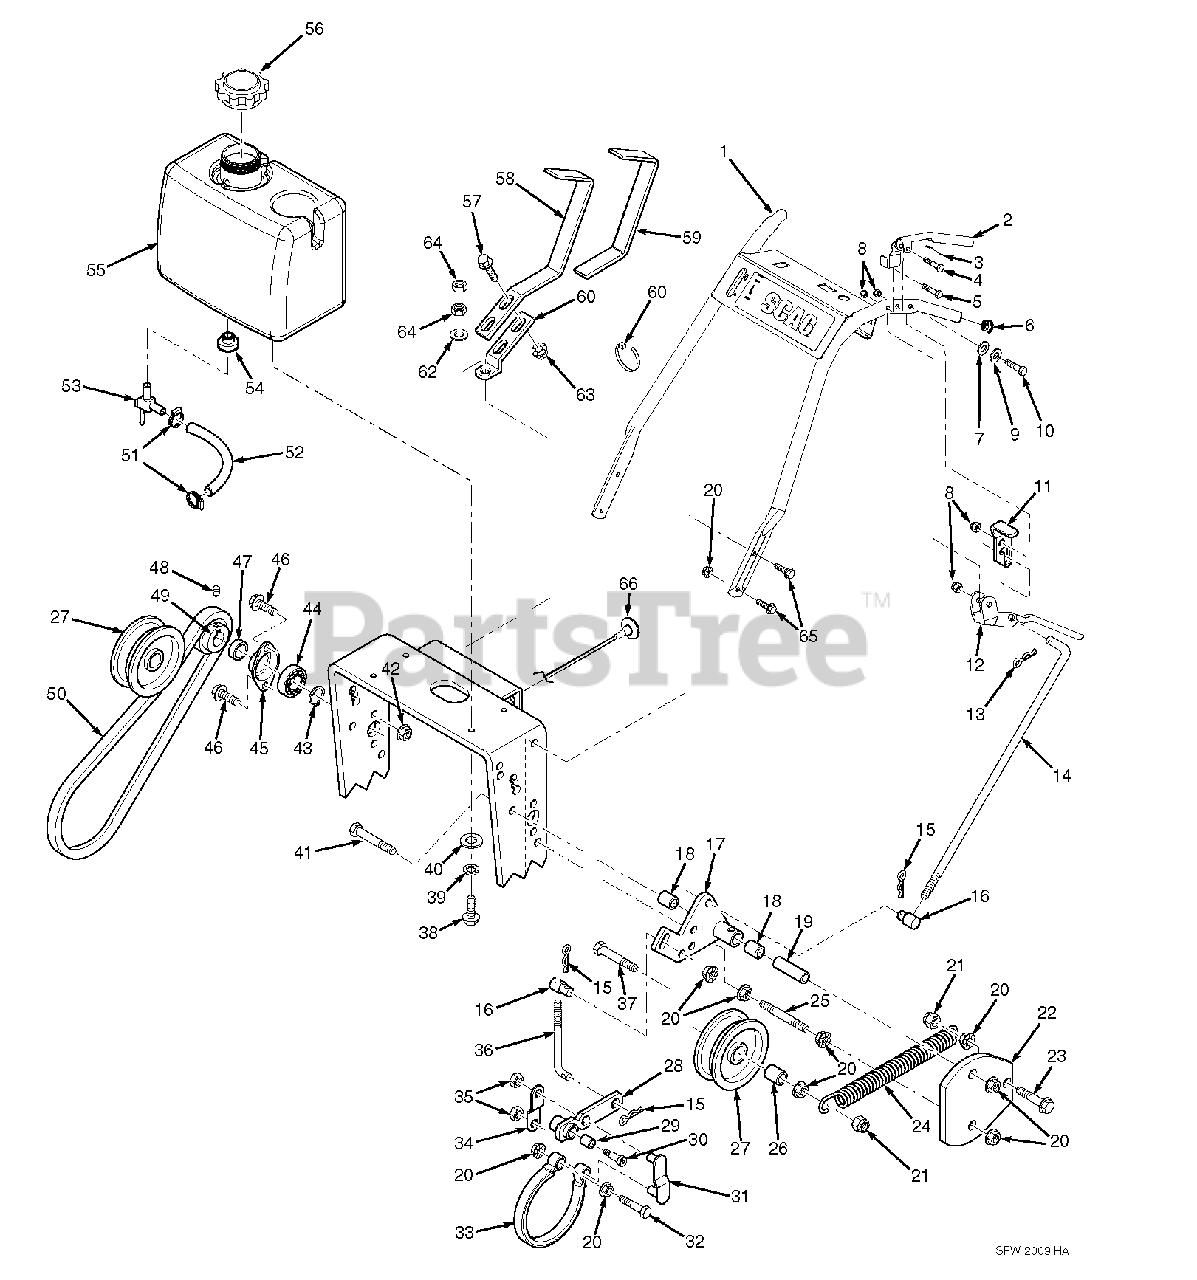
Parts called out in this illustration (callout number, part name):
1	Handle Weldment w/Decals
2	Operator Presence Handle, LH
3	Spring, Operator Presence
4	Bolt, Hex Head 5/16-18 x 2-3/4"
5	Bolt, Hex Head 5/16-18 x 2-1/2"
6	Plug, Handle Bar
7	Washer, Curved Spring
8	Nut, Elastic Stop 5/16-18
9	Flatwasher, 5/16-.375 x .875 x .083
10	Bolt, Hex Head 5/16-18 x 2"
11	Neutral Latch Assembly, LH
12	Lever, Steering Brake
13	Hair Pin Cotter
14	Rod, Steering Control
15	Hair Pin Cotter
16	Swivel Joint
17	Idler Bracket Assembly, RH
18	Bearing
19	Sleeve
20	Nut, Serrated Flange 3/8-16
21	Nut, Elastic Stop 3/8-16
22	Belt Guard
23	Bolt, Serrated Flange 3/8-16 x 1-1/4"
24	Spring
25	Stud, 3/8-16 x 5"
26	Spacer
27	Pulley, Idler 5"
28	Lever Weldment, Brake w/Bearing
29	Bearing
30	Bolt, Shoulder 1/2 x 1"
31	Link Weldment, Brake
32	Bolt, Hex Head 3/8-16 x 2"
33	Brake Band Assembly
34	Link, Brake
35	Nut, Push-On
36	Rod, Brake
37	Bolt, Hex Head 3/8-16 x 3-1/4"
38	Bolt, Hex Head 5/16-18 x 1"
39	Lockwasher, 5/16" Spring
40	Flatwasher, 5/16-.375 x .875 x .083
41	Bolt, Hex Head 3/8-16 x 4-1/2"
42	Nut, Serrated Flange 1/4-20
43	Retaining Ring, 5/8" Ext.
44	Bearing, Jackshaft
45	Flange, Jackshaft Bearing
46	Bolt, Serrated Flange 1/4-20 x 3/4"
47	Spacer, Jackshaft
48	Set Screw, Hex Socket 5/16-18
49	Pulley, Jackshaft 3.25 OD x .625 Bore
50	Belt, Wheel Drive
51	Clamp, 1/4" ID Fuel Hose
52	Fuel Hose, 1/4" ID
53	Valve, Fuel Shutoff w/Screen
54	Bushing, .56 Dia. Viton
55	Fuel Tank Assembly
56	Cap, Fuel Tank
57	Bolt, Serrated Flange 5/16-18 x 1"
58	Shift Lever Extension w/Grip
59	Grip, Shift Handle
60	Cable Tie
61	Shift Lever
62	Flatwasher, 3/8-.391 x .938 x .105
63	Nut, Serrated Flange 5/16-18
64	Nut, 3/8-24 UNF
65	Bolt, Serrated Flange 3/8-16 x 1"
66	Choke Control
